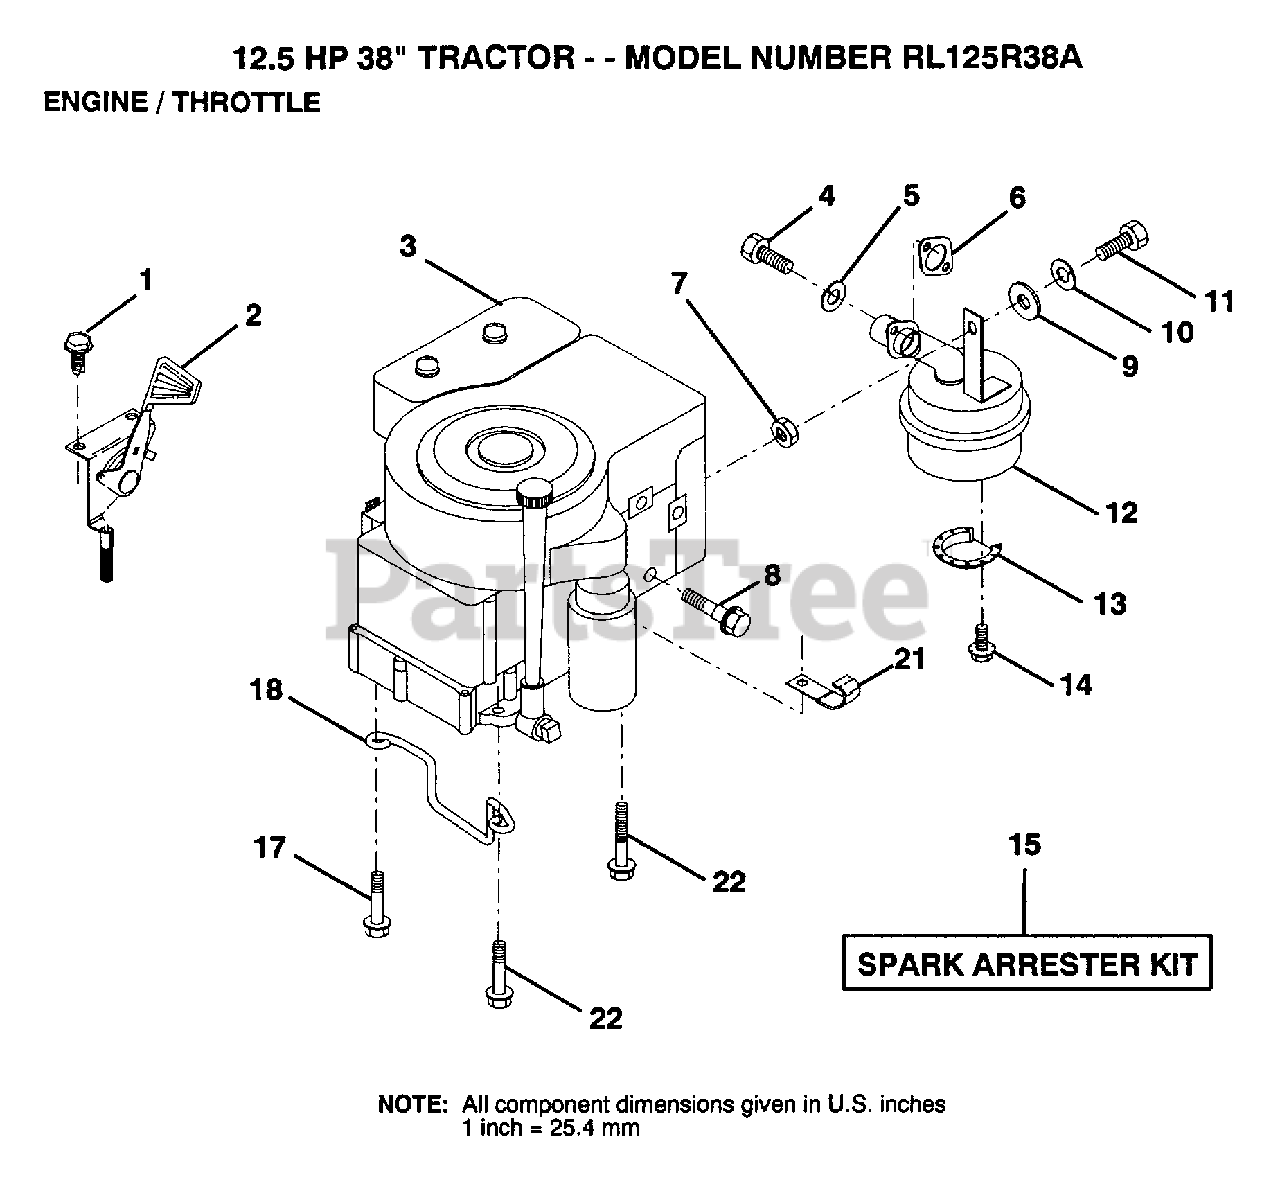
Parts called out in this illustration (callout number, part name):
1	SCREW
2	THROTTLE CONTROL
4	SCREW
5	LOCKWASHER
7	NUT.HEX.5/16-18
8	BOLT T
10	LOCKWASHER
12	MUFFLER
13	DEFLECTOR.222573
17	SCREW LT
18	"KEEPER,DR BELT GR"
21	CLIP T
22	SCREW LT
